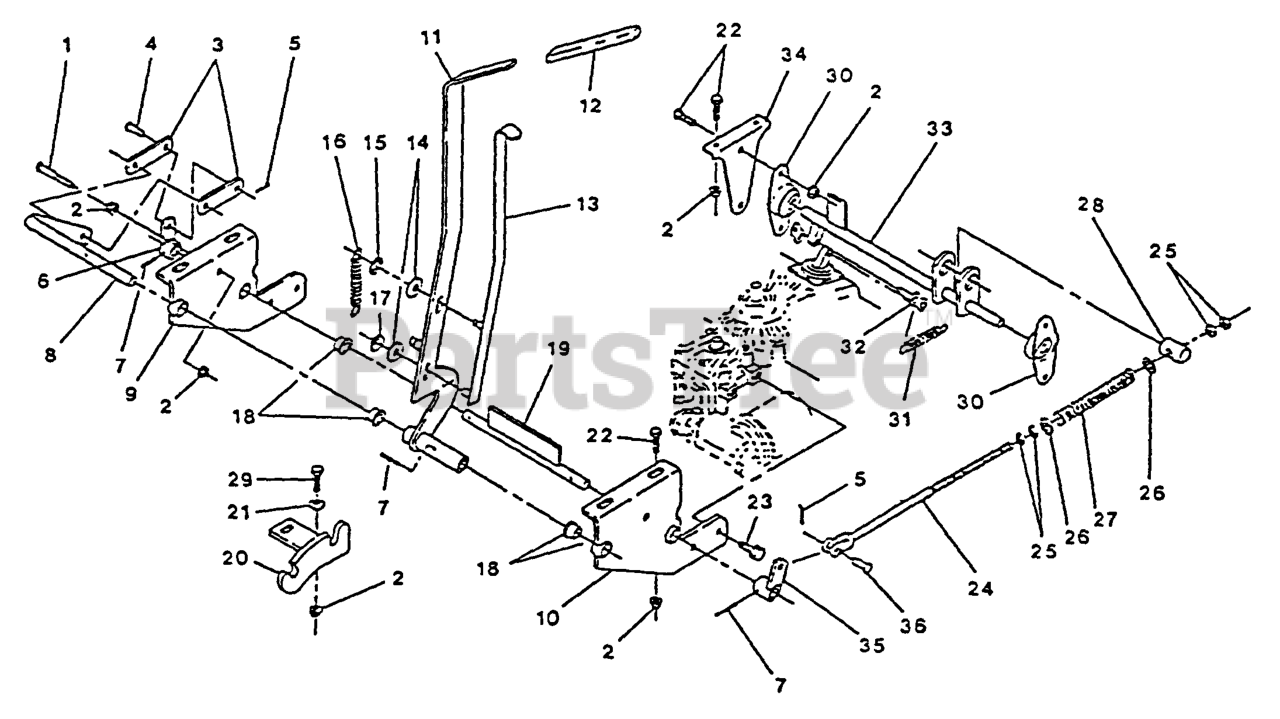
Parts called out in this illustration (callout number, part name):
3	LINK,BRAKE PLTD
4	PIN-CLEVIS
6	WLD,CONTROL ARM
8	PIVOT - BRKT/LEVER
12	GRIP-LEVER
16	SPRING,BRAKE HANDLE
17	NUT,PUSH
18	BEARING-CONTROL
19	WLD,BUTTERFLY
20	WLD,BRAKE QUADRANT
21	WASHER-SPRING
24	LINKAGE,BRAKE
27	SPRING,COMPRESSION
28	PIN,TRUNION
30	FLANGE MTG, SIDE
32	LINK-CONN#60
35	WLD,BRAKE CONTROL ARM
36	PIN-CLEVIS
